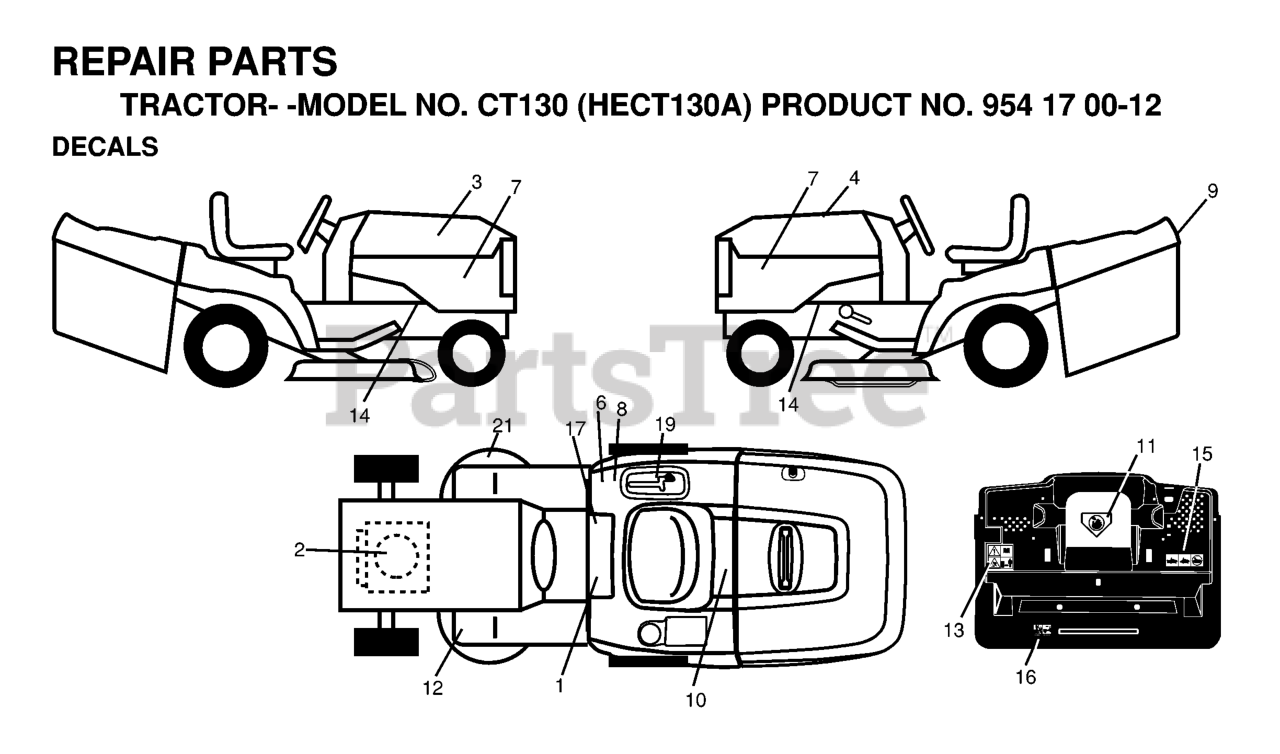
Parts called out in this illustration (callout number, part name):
1	DECAL READ OWNER'S MAN SYMS
2	DECAL
6	DECAL CERTIFICATION
7	DECAL PNL SIDE
8	DECAL EUROPE STANDARD CE
9	DECAL FENDER HUSQ
10	DECAL BTRY SYMBOLS
11	DECAL MOWER CUT/FINGER
12	DECAL
13	Decal Warn Back Plate CRD
14	DECAL
15	DECAL
16	DECAL
17	DECAL PARK BRAKE
19	DECAL
21	DECAL
